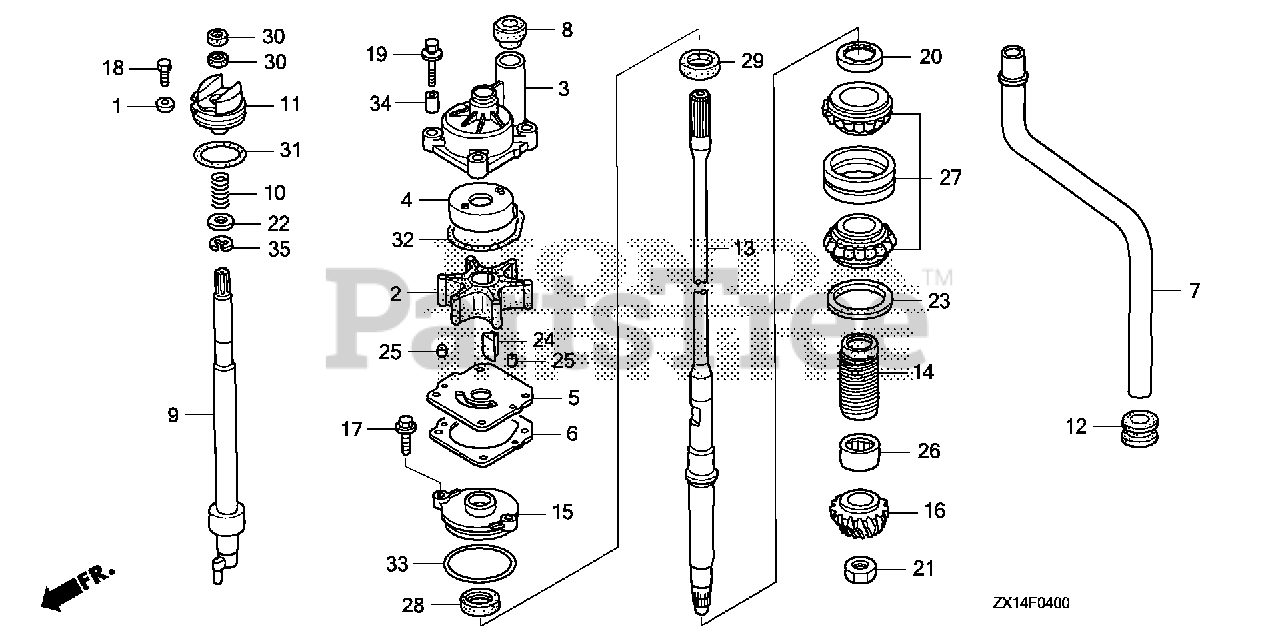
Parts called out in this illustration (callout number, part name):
1	WASHER, PIVOT
2	IMPELLER, PUMP
3	HOUSING, IMPELLER
4	LINER, PUMP
5	COVER, IMPELLER
6	GASKET B, IMPELLER
7	TUBE, WATER (L)
8	RING, WATER TUBE SEAL
9	ROD, SHIFT
10	SPRING, SHIFT ROD
11	HOLDER, SHIFT ROD
12	GROMMET, EXTENSION CASE
13	SHAFT, VERTICAL (L)
14	SLINGER, OIL
15	HOUSING, WATER SEAL
16	GEAR, PINION
17	BOLT, FLANGE (6X20) (ENGINE NO.)
18	BOLT, HEX. (6X12) Use up to Frame SN 1005248.
19	BOLT-WASHER (8X40)
20	NUT, LOCK (64MM)
21	NUT, HEX. (18MM)
22	WASHER, PLAIN (12MM)
23	SHIM A, GEAR (0.10)
23	SHIM B, GEAR (0.15)
23	SHIM C, GEAR (0.30)
23	SHIM D, GEAR (0.50)
24	KEY, WOODRUFF
25	PIN, DOWEL (6X10)
26	BEARING, NEEDLE (28.575X44.45X31.75)
27	BEARING, TAPER ROLLER (30X62X40)
28	SEAL, WATER (23X36X8)
29	SEAL, WATER (23X36X6)
30	SEAL, WATER (12X21X6)
31	O-RING (55.6X3.5)
32	O-RING, WATER PUMP
33	O-RING (58.5X3.5)
34	COLLAR, DISTANCE
35	E-RING (10MM)
